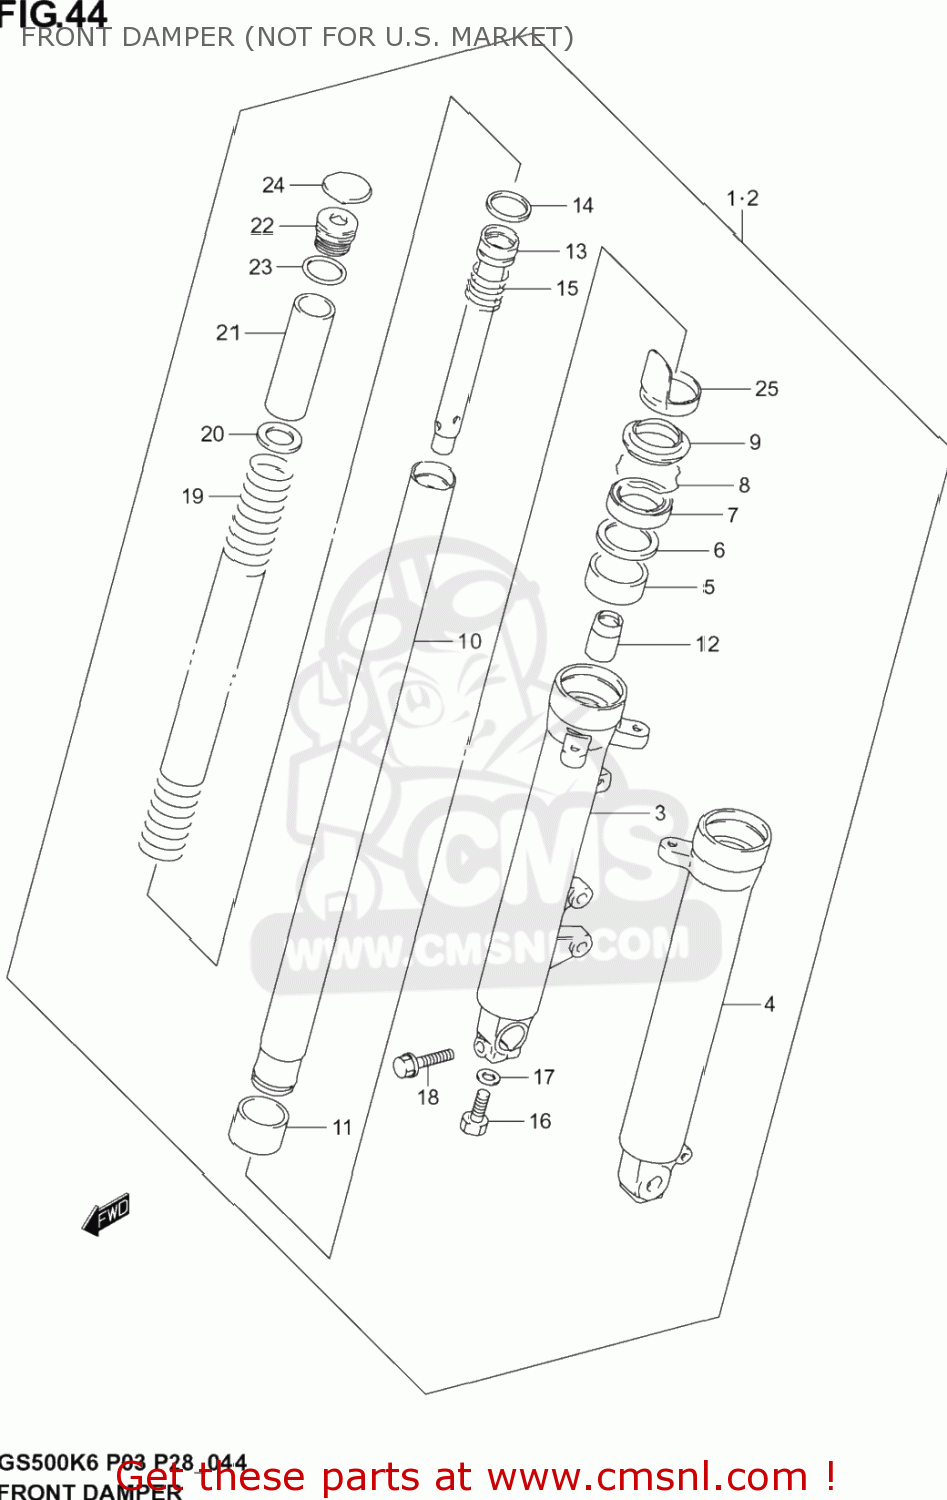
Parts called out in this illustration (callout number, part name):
1	DAMPER ASSY,FR FORK,R
2	DAMPER ASSY,FR FORK,L
3	TUBE,OUTER,R
4	TUBE,OUTER,L
5	METAL,SLIDE
6	WASHER
7	SEAL,OIL
8	RING,STOPPER
9	SEAL,DUST
10	TUBE,INNER
11	PISTON
12	PIECE,OIL LOCK
13	CYLINDER
14	RING,PISTON
15	SPRING,REBOUND
16	BOLT,FORK CYLINDER(10X25)
17	GASKET (NAS)
18	BOLT
19	SPRING,MAIN
20	WASHER
21	SPACER
22	WASHER,UPR
23	BOLT,FORK
24	O RING
25	PROTECTOR,FR FORK
